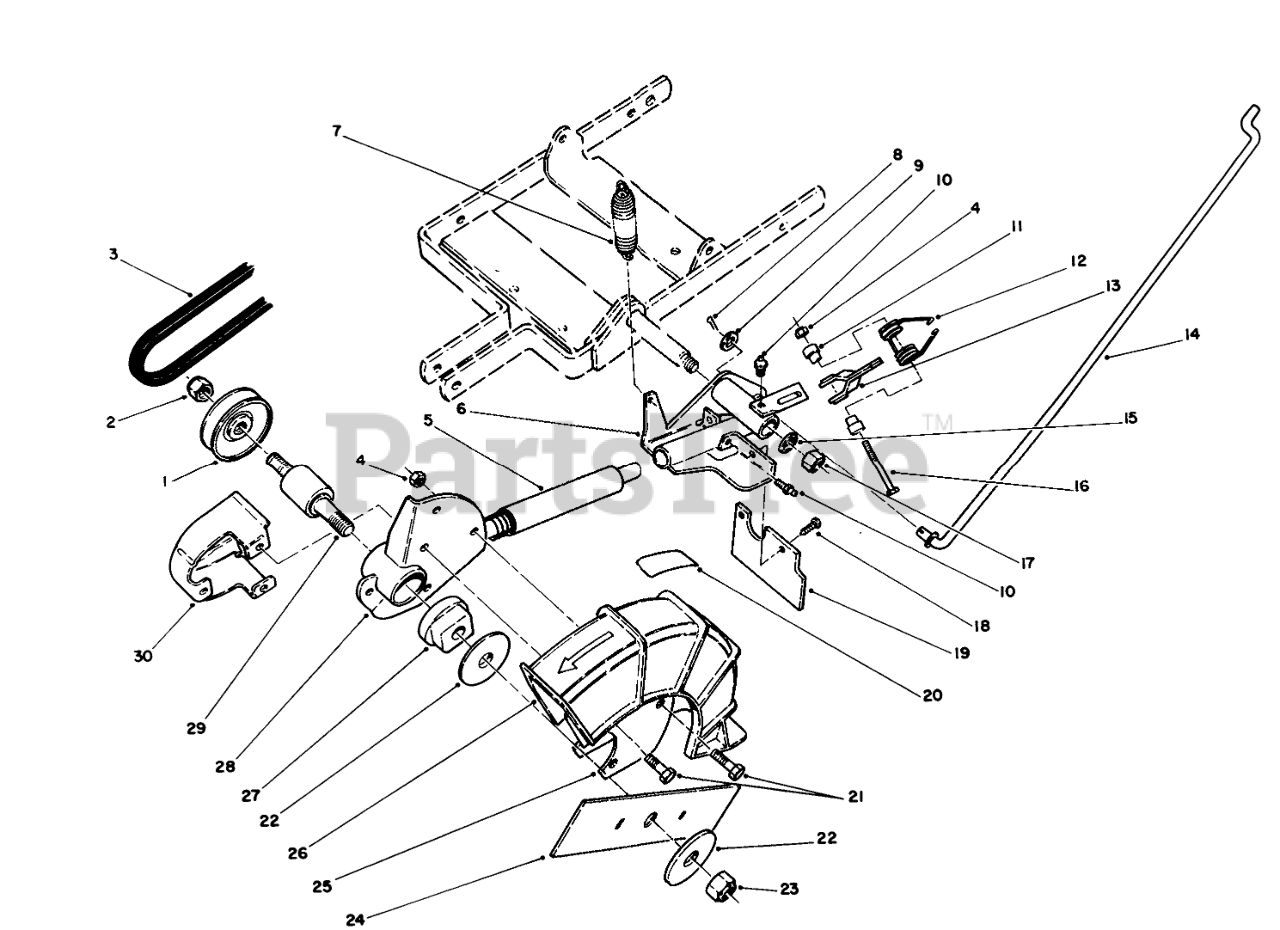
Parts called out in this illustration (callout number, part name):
1	PULLEY
2	NUT-LOCK, NI
3	V-BELT
4	NUT-LOCK, NI
5	SPRING & BELLOW ASM
6	PIVOT ARM WELDMENT B
7	EXT. SPRING
8	PIN-COTTER
9	WASHER-FLAT
10	FITTING-GREASE
11	SPACER-PIVOT LEVER
12	TORSION SPRING
13	LEVER WA
14	LOWER CONTROL ROD
15	WASHER-PLAIN
16	SCREW-HH
17	NUT-LOCK, NI
18	PANEL FASTENER
19	RUBBER GUARD
20	DECAL-BLADE
21	SCREW-HWHTF
22	WASHER-LARGE
23	NUT-HEX
24	10" EDGER BLADE B
25	GUARD PLATE
26	Guard-Blade (Incl. Ref. #20)
27	BRG SHIELD
28	HUB ASM
29	SPINDLE ASM
30	PULLEY GUARD WA
